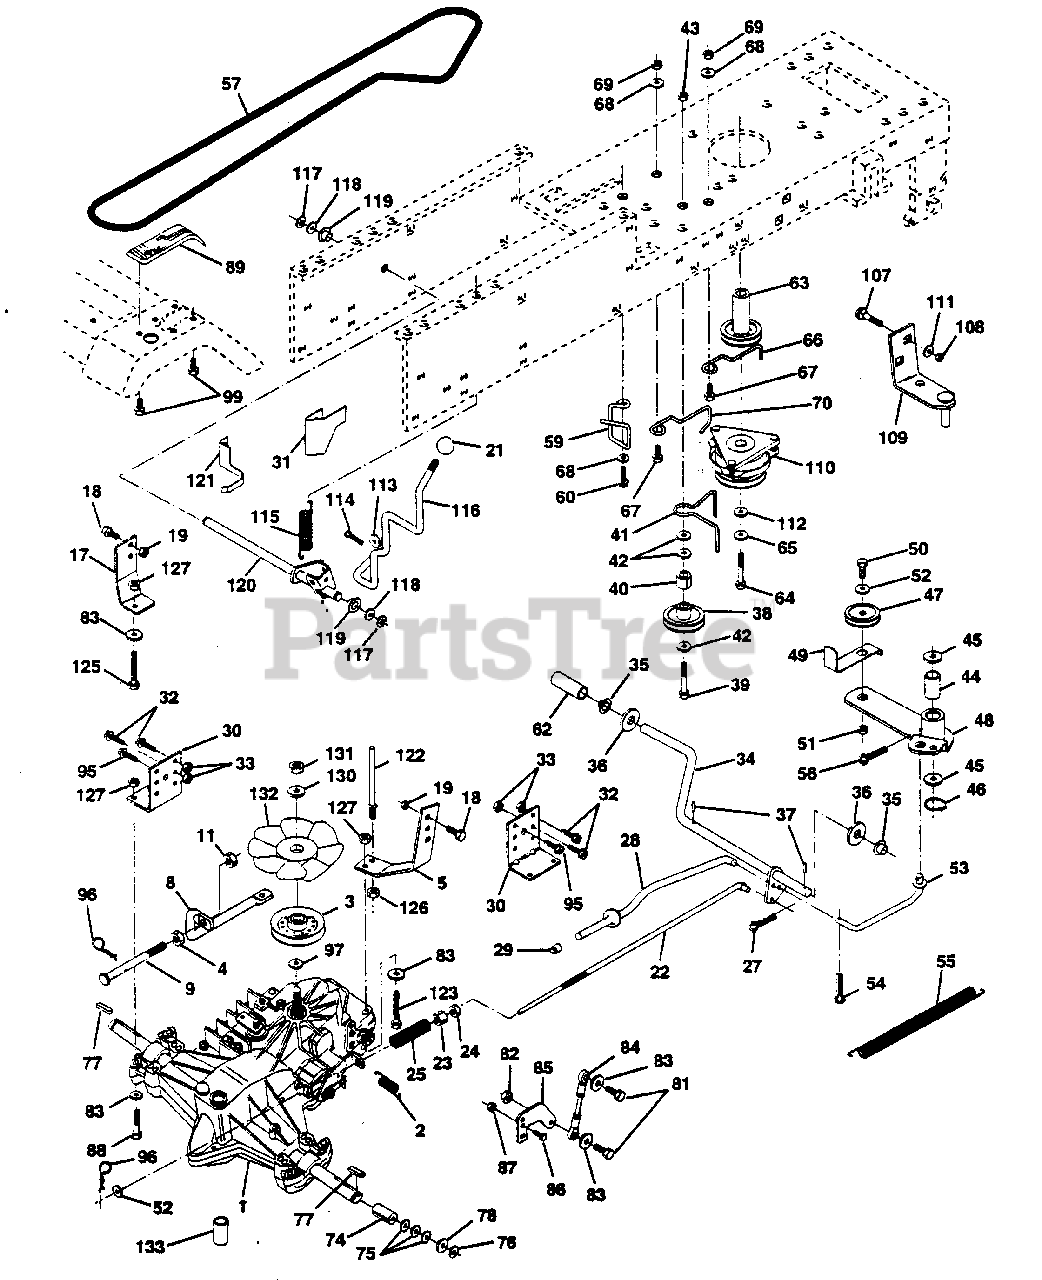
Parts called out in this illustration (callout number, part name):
1	Transaxle Assembly (AYP part number)
2	Spring, Return, Brake (AYP part number)
3	Pulley, Transaxle (AYP part number)
4	Nut Hex Jam 5/16-18 Unc (AYP part number)
5	Strap Torque Rh Hydro 18/20" T (AYP part number)
8	Control Bypass Hydro 18" Tires (AYP part number)
9	Rod Bypass Hydro 18/20" (AYP part number)
11	Nut Lock Hex W/Ins 5/16-18 Unc P (AYP part number)
17	Strap Torque Lh Hydro 18/20" T (AYP part number)
18	Bolt Fin Hex 3/8-16 Unc x 1 Gr. 5 (AYP part number)
19	Nut Lock Hex W/Wsh 3/8-16 Unc (AYP part number)
21	Knob, Duckhead 1/2-13 (AYP part number)
22	Rod, Brake Hydro (AYP part number)
23	Nut (AYP part number)
24	Locknut (AYP part number)
25	Spring, Brake Rod (AYP part number)
27	Pin Cotter 1/8 x 3/4 CAD. (AYP part number)
28	Rod, Parking Brake (AYP part number)
29	Cap, Parking Brake (AYP part number)
30	Bracket, Transaxle (AYP part number)
31	Keeper Belt Lh (AYP part number)
32	Bolt Hex Hd 5/16-18 Unc x 3/4 (AYP part number)
33	Nut Lock Hex W/Ins. 5/16-18 Unc (AYP part number)
34	Shaft, Foot Pedal (AYP part number)
35	Bearing, Nylon (AYP part number)
36	Washer (AYP part number)
37	Pin, Roll (AYP part number)
38	Pulley, Idler, Flat (AYP part number)
39	Bolt (AYP part number)
40	Spacer, Split (AYP part number)
41	Keeper, Belt Retainer (AYP part number)
42	Washer 13/32 x 13/16 x 12 Gauge (AYP part number)
43	Nut (AYP part number)
44	Bearing, Nylon (AYP part number)
45	Washer, Hardened (AYP part number)
46	Ring, Klip (AYP part number)
47	Pulley, Idler, V-Groove
48	Bellcrank Assembly (AYP part number)
49	Retainer, Belt (AYP part number)
50	Bolt (AYP part number)
51	Nut
52	Washer (AYP part number)
53	Link, Clutch (AYP part number)
54	Pin (AYP part number)
55	Spring, Return, Clutch (AYP part number)
56	Pin (AYP part number)
57	V-Belt, Ground Drive (AYP part number)
59	Keeper, Center Span (AYP part number)
60	Screw Thdrol. 3/8-16 x 3/4 Ty. TT (AYP part number)
62	Cover, Pedal (AYP part number)
63	Pulley, Engine (AYP part number)
64	Bolt, Hex (AYP part number)
65	Washer (AYP part number)
66	Keeper Belt Engine (AYP part number)
67	Bolt (AYP part number)
68	Washer 13/32 x 13/16 x 12 Gauge (AYP part number)
69	Nut (AYP part number)
70	Keeper Belt Engine (AYP part number)
74	Spacer, Split (AYP part number)
75	Washer 25/32 x 1-1/4 x 16 Gauge (AYP part number)
76	E-Ring (AYP part number)
77	Key, Square (AYP part number)
78	Washer 25/32 x 1-5/8 x 16 Gauge (AYP part number)
81	Bolt Fin Hex 5/16-18 Unc x 1-1/4 (AYP part number)
82	Nut Lock Hex W/Ins. 5/16-18 Unc P (AYP part number)
83	Washer 11/32 x 3/4 x 16 Ga. (AYP part number)
84	Rod, Tie Hydro 18" Tires (AYP part number)
85	Arm, Control Hydro (AYP part number)
86	Screw Cap Hex 5/16 x 18 x 1 (AYP part number)
87	Nut Lock Hex W/Ins. 5/16-18 Unc P (AYP part number)
88	Bolt Fin Hex 5/16-18 Unc (AYP part number)
89	Console, Shift (AYP part number)
95	Screw, Thdroll. 3/8-16 x 1 Type TT (AYP part number)
96	Retainer Spring 1" Zinc/Cad (AYP part number)
97	Washer 21/32 x 1 x 16 Ga. (AYP part number)
99	Screw (AYP part number)
107	Bolt Carriage 5/16-18
108	Nut, Crownlock 5/16-18
109	Bracket, Asm Mtg Clutch (AYP part number)
110	Clutch, Electric (AYP part number)
111	Washer 11/32 x 5/8 x 12 Ga. (AYP part number)
112	Washer 1-1/2 OD x 15/32 ID x .250 (AYP part number)
113	Washer 17/32 x 3/4 x 16 Ga. (AYP part number)
114	Pin Cotter 1/8 x 1 CAD (AYP part number)
115	Spring Torsion T/A (AYP part number)
116	Rod Shift Fender YT (AYP part number)
117	Ring Klip #5304-62 (AYP part number)
118	Washer 21/32 x 1-1/4 x 16 Ga. (AYP part number)
119	Bushing Rod Steering 629/632 ID (AYP part number)
120	Shaft Asm. Cross Hydro 20" Tires (AYP part number)
121	Keeper Belt Lh Hydro 0750. 18/20" (AYP part number)
122	Keeper Belt Rh Hydro 0750. 18/20" (AYP part number)
123	Bolt Fin Hex 5/16-18 x 2-1/4 (AYP part number)
125	Bolt Fin Hex 5/6-18 Unc x 1-1/2 (AYP part number)
126	Nut Keps Hex 3/8-16 Unc (AYP part number)
127	Nut Lock Hex W/Ins 5/16-18 Unc P (AYP part number)
130	Washer Belleville .501D x 1.50D (AYP part number)
131	Nut Nylon Insert 1/2-20 Unf. (AYP part number)
132	Fan, Hydro 7" (AYP part number)
133	Line Fuel Hydro 4" (AYP part number)
